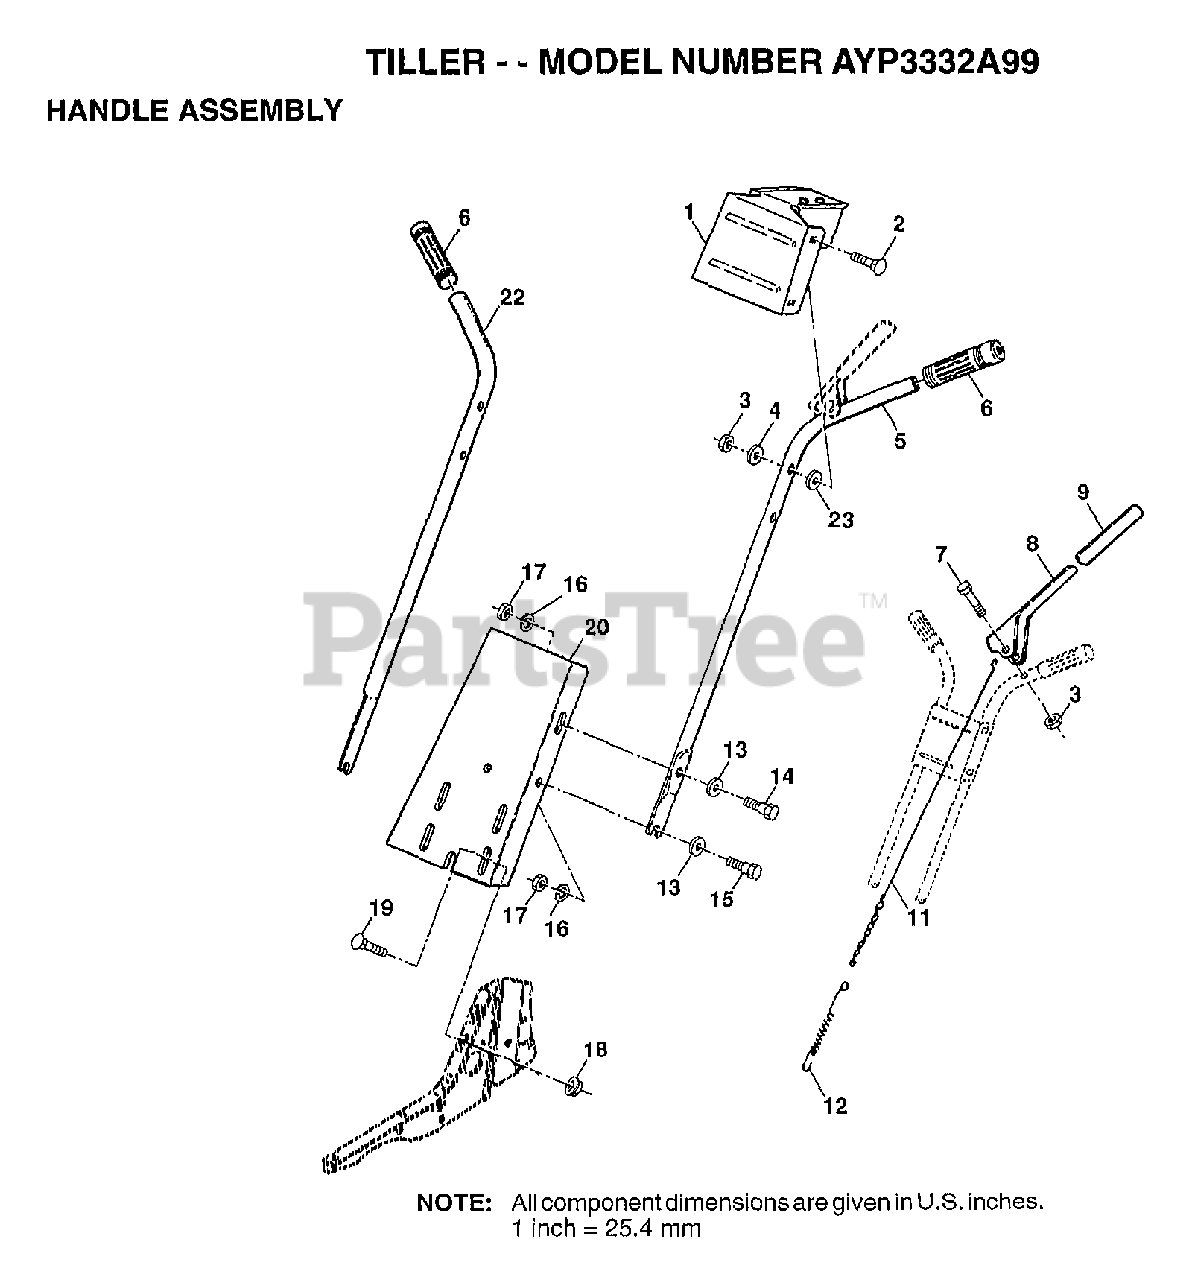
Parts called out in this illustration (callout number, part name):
1	HANDLE BRKT
2	BOLT
4	WASHER
5	HANDLE LH
7	BOLT.HEX.5/16-1.5
8	LEVER.CONTROL.TINE
9	GRIP T
12	SPRING EXT TI
13	WASHER
15	BOLT
16	LOCKWASHER
17	NUT.HEX.5/16-18
18	NUT
19	BOLT
20	PANEL. HANDLE
22	HANDLE RH
23	WASHER
